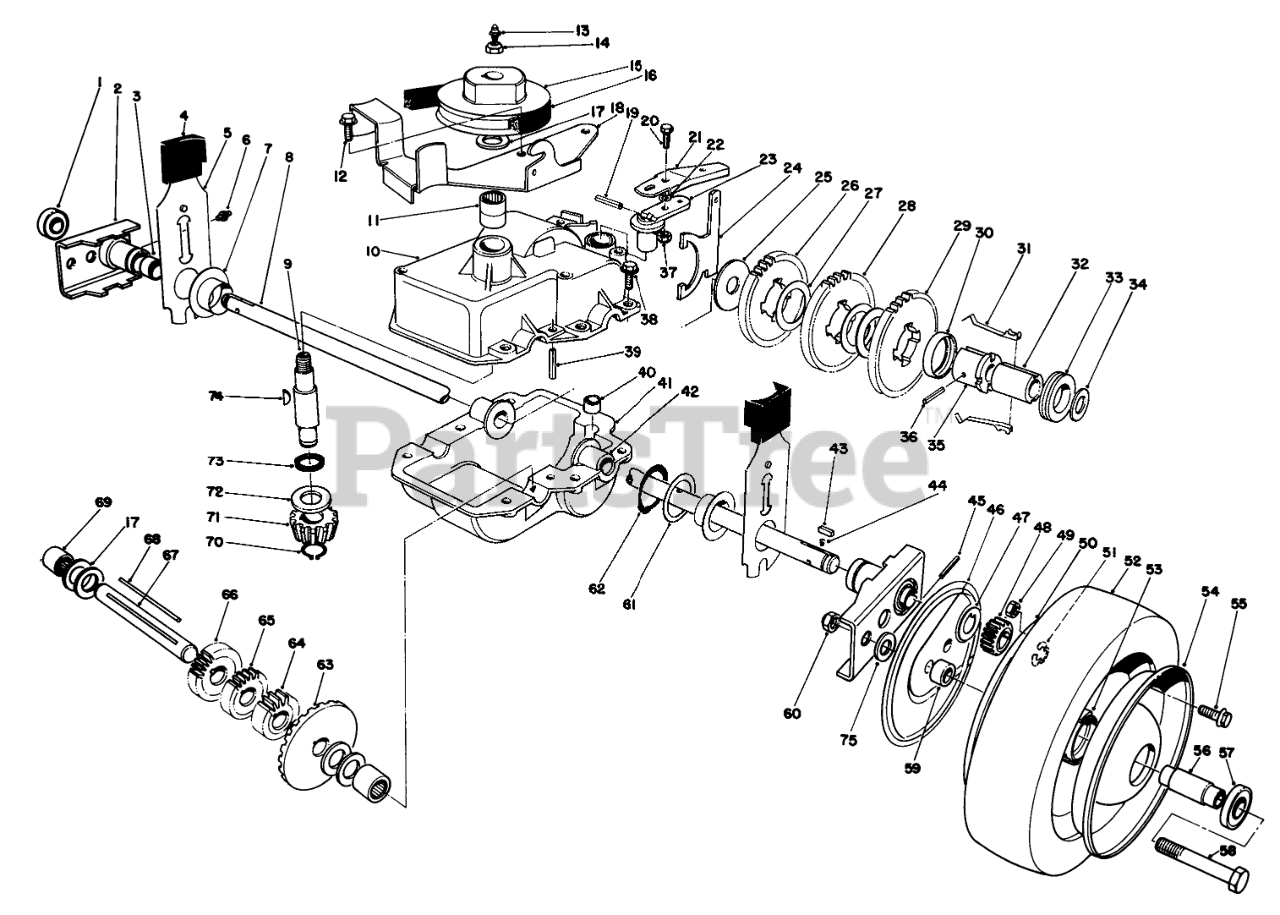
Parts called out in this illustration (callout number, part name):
1	Ball Bearing
2	Pivot Arm Assembly (Incl. Ref.#1, 3, & 6)
3	BUSHING
4	KNOB-ARM
5	Spring Arm Assembly-Rear
6	FITTING-GREASE
7	CAP-END
8	Shaft-Output
9	Shaft Input
10	Upper Case Assembly (Incl. Ref.#11 & 73)
11	BEARING-NEEDLE
12	SCREW
13	FITTING-GREASE
14	NUT-HEX
15	PULLEY
16	V-BELT
17	WASHER-THRUST
18	Belt Guide Bracket
19	PIN-COIL
21	SHIFT LEVER COVER
22	WASHER-FLAT
23	LEVER-SHIFT
24	Shift Yoke
25	WASHER
26	GEAR-38T
27	WASHER
28	GEAR-42T
30	RETAINER-KEY
31	KEY-SHIFT
32	SLEEVE
33	COLLAR-SHIFT
34	WASHER-PLAIN
35	SLEEVE-GEAR
36	PIN-GROOVE
37	NUT-LOCK, NI
38	SCREW-HWHTF
39	PIN-ROLL
40	BUSHING-YOKE
41	Case-Lower
42	BUSHING
43	KEY RECTANGULAR
44	SPRING-COMPRESSION
45	Pin
46	WHEEL COVER
47	WASHER-THRUST, OUTER
48	GEAR-PINION
49	NUT-LOCK, NI
50	Wheel-Half
51	RING-RETAINING
53	HUB-BEARING
54	Wheel-Half
55	SCREW-HHF
56	SPACER-BEARING
57	BEARING-WHEEL
58	SCREW-HH
59	SPACER-WHEEL
60	NUT-LOCK, CONE
61	WASHER
62	RING-RETAINING
63	BEVEL GEAR
64	GEAR-12T
65	GEAR-14T
66	GEAR-18T
67	SHAFT-INTERMEDIATE
69	BEARING-NEEDLE, CLOSED
70	RING-RETAINING
71	PINION-BEVEL
72	WASHER-THRUST
74	KEY-WOODRUFF
75	WASHER
